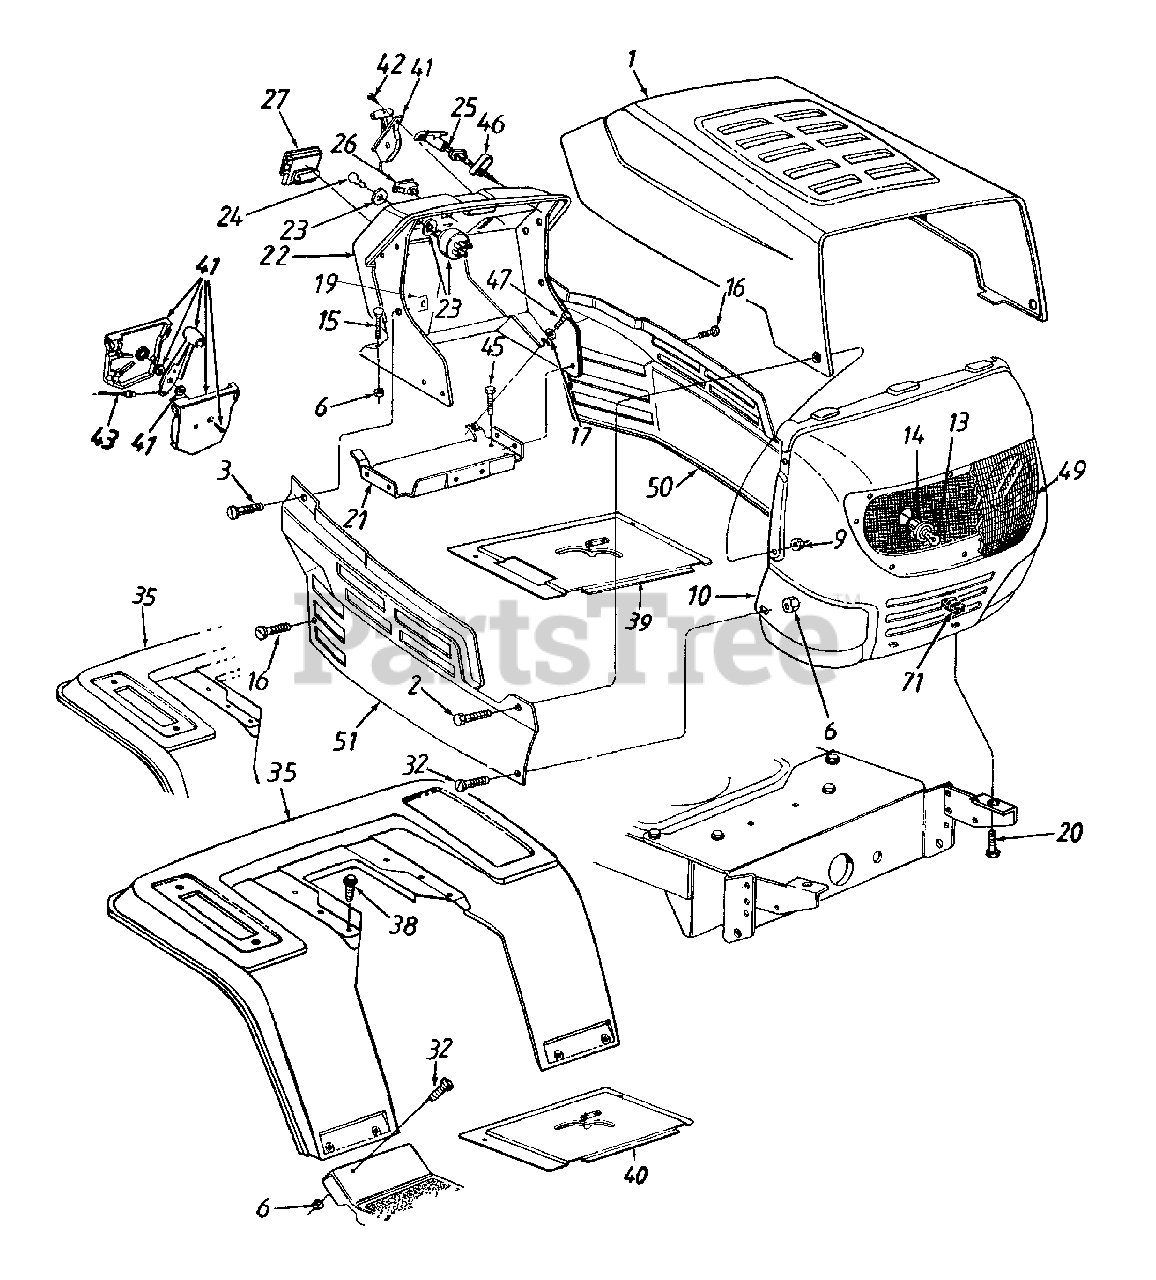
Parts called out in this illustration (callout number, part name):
3	Pan Hd. Scr. 1/4-20 x .75" Lg.
6	Hex Nut 1/4-20 Thd.
9	Flange L-Nut 1/4-20 Thd.
13	Lamp
14	Socket
15	Carriage Bolt 1/4-20 x .75" Lg.
16	Hex Wash. Hd. TT-Tap Scr.1/4-20
17	Fl-Wash. .281" I.D. x .73" O.D.
19	Speed Nut 1/4-20 Thd.
20	Hex Bolt 5/16-18 x 1" Lg. (Gr.5)
23	Ignition Switch
24	Ignition Key
25	Choke Control 23" Lg.
26	Light Switch
27	Ammeter
41	Throttle Box Ass'y.
42	Truss Mach. AB-Tap Scr.#10 x .5"
43	Throttle Control Wire 18.5" Lg.
45	Hex Wash. Hd. B-Tap Scr.5/16-18
46	Choke Retainer
47	Hex TT-Tap Scr. 1/4-20 x .75" Lg.
49	Lens
